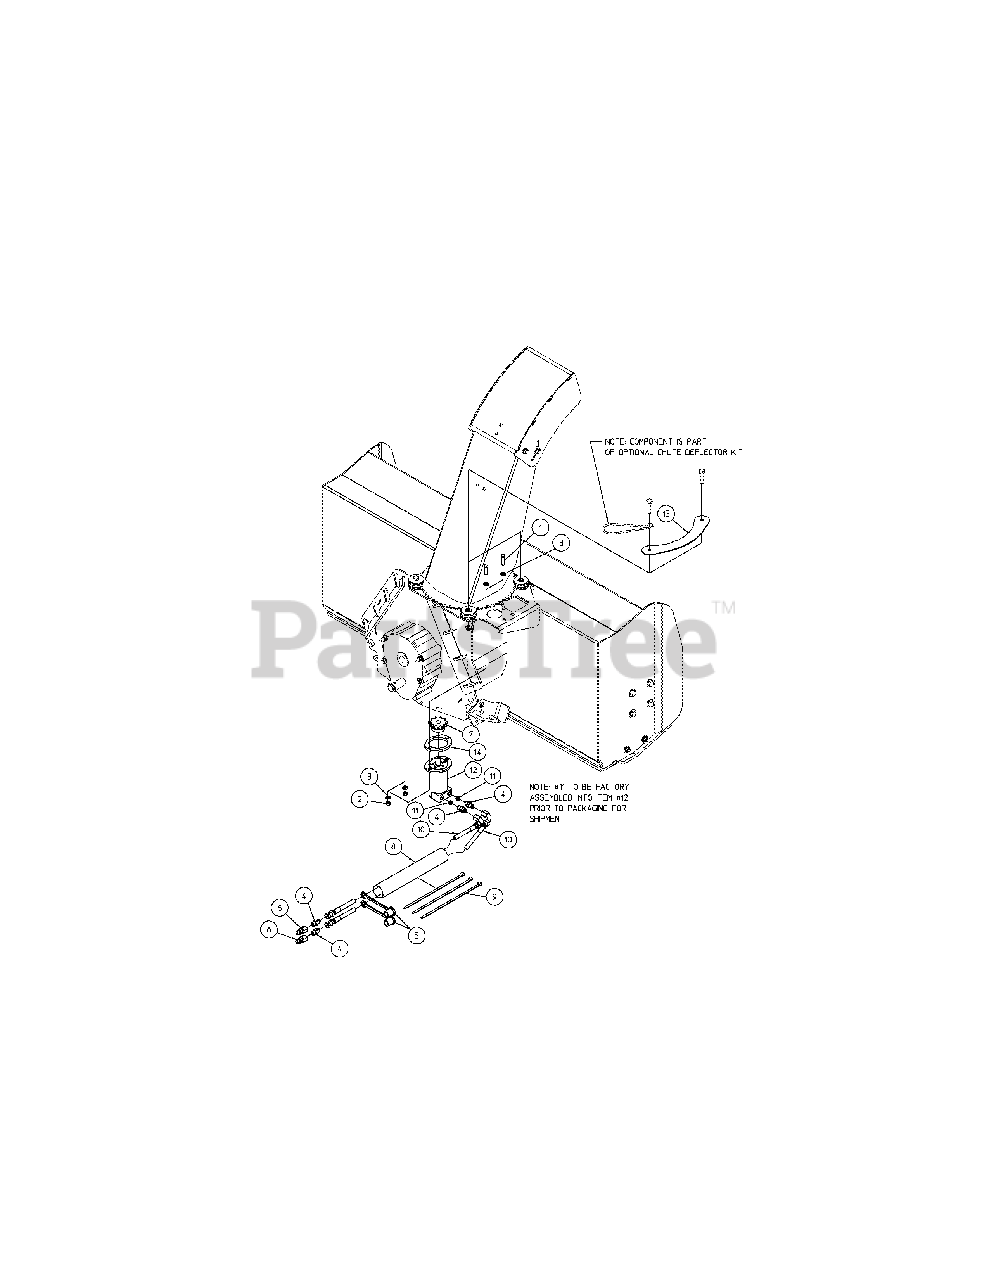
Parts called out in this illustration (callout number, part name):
1	HEX HEAD CAP SCREW, 5/16-18 X 1.25 GR 5
2	LOCK NUT, HEX 5/16-18 GR 5
3	FLAT WASHER, 5/16 SAE
4	ADAPTER UNION, STR
5	DUST CAP, BLACK
6	COUPLER NOSE
8	HOSE SLEEVE
9	PLASTIC TIE
10	HYDRAULIC HOSE, 1/4 X 87
11	RESTRICTOR
12	HYD MOTOR, SIDE PORT
13	GUARD SPROCKET PLATE
